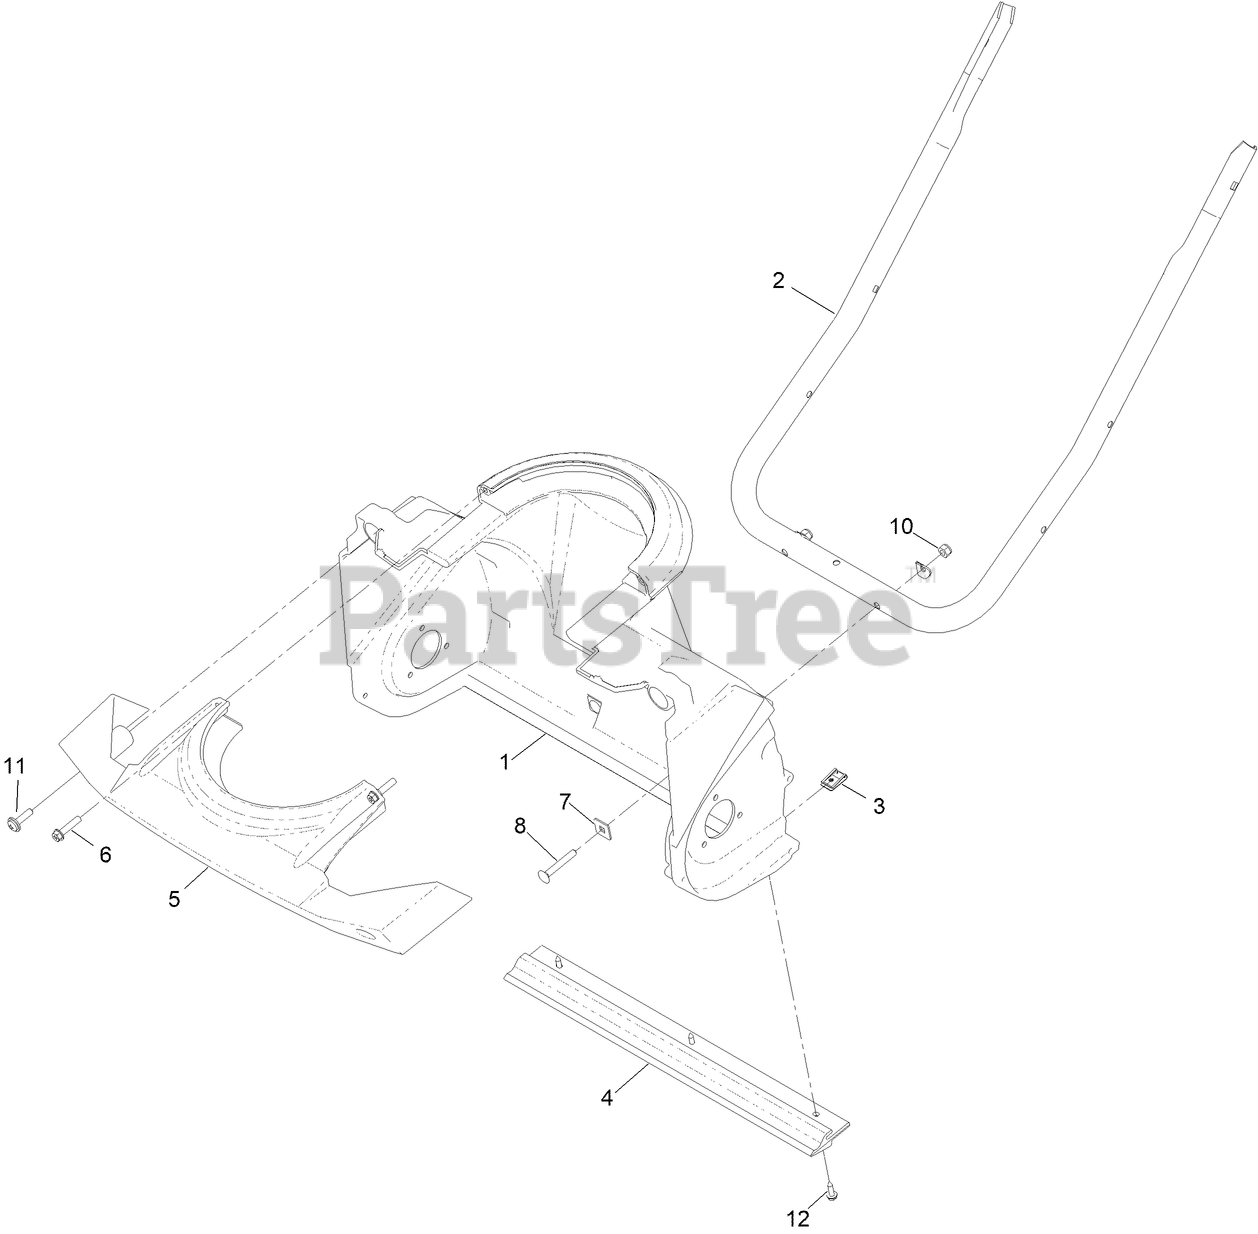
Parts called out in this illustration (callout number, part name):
1	HOUSING-ROTOR
2	HANDLE-LOWER
3	NUT-CLIP, U
4	SCRAPER
5	BUMPER-FRONT
6	SCREW-PLASTIC,HWH
7	WASHER-SQUARE
8	BOLT-CARR
10	NUT-LOCK, NI
11	SCREW-PPH, SEMS
12	SCREW-THD FORM,HWH
